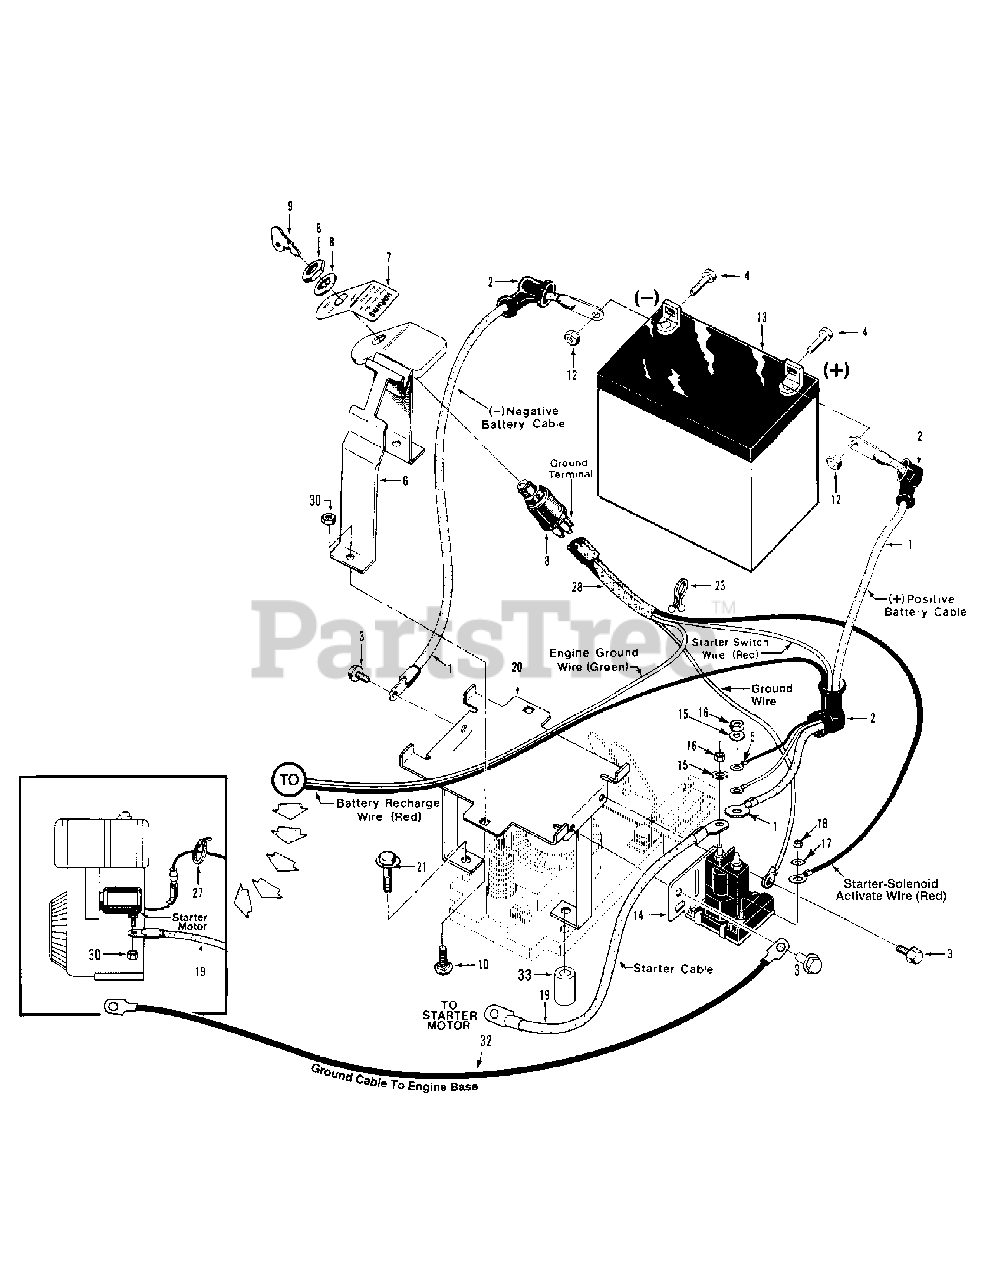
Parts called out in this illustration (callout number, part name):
1	Cable-battery, positive and negative terminals
2	Boot-terminal insulating
3	Screw-TT, 1/4-2 x 2
4	Bolt-hex hd., 1/4-20
5	Wire-recharge (red)
6	Battery Hold Down Clamp - with attached Key Switch Plate
7	Decal-ignition switch instructions
8	Key Switch-includes 2 ignition keys (Ref. No.9) one lockwasher, and one mounting nut (lock-washer and nut not available separately)
9	Key-ignition, one pair
10	Bolt-carriage, 1/4-20 x 1-1/4"
11	Lockwasher-spring lock, 1/4"
12	Nut-hex, 1/4"-20
13	Battery-12 volt,
14	Solenoid-starter, includes nuts and washers for cables and wires
15	Lockwasher-5/16"
16	Nut-hex, 5/16"-24
17	Lockwasher-external tooth, #10
18	Nut-hex, #10-32,
19	Cable-solenoid to starter motor
20	Battery Bracket
21	HH Cap Screw, 3/8-16 x 2.75"
23	Tie-plastic, wire
27	Tie-plastic
28	Wire Harness & Connecting Terminal Assembly
30	Locknut-hex, 1/4-20
32	Cable-ground, solenoid to engine block
